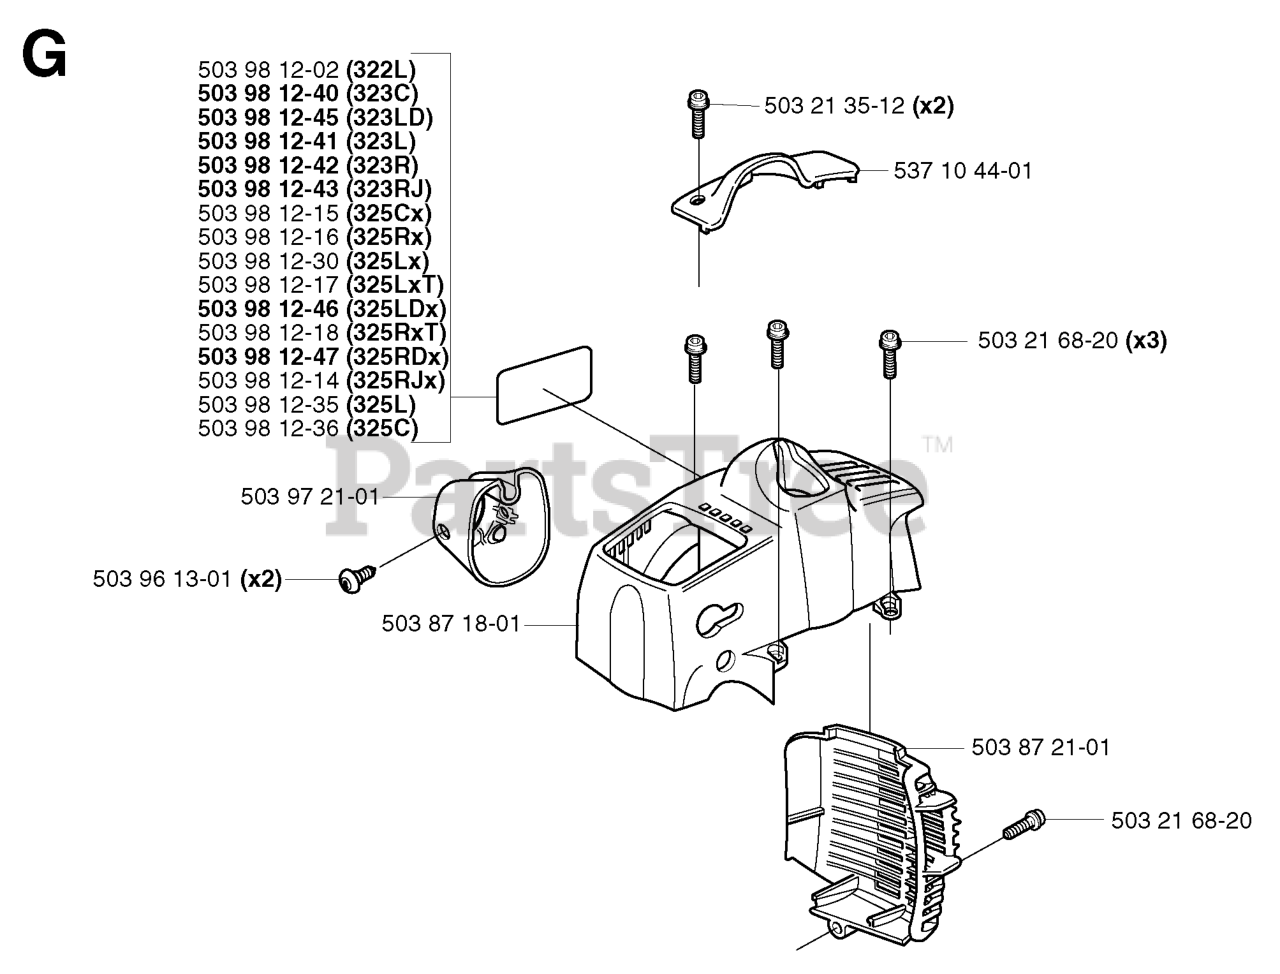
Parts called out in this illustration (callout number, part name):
1	BRACKET.SHIFT.HYDRO
2	SCREW #10-24 X 5/8
3	SCREW 5/16-18 X 3.25
4	WASHER, NYLON FRICTION
5	THRUST WASHER
6	WASHER.20X8.5
7	SRPING.FRICTION.HYDRO
8	NUT.71038.31-18.HEX.NYLOCK
9	BRACKET.HYD.CLUTCH.
10	ARM.CONTRL.PIN.TRACK
11	CONTROL.SHAFT.ASM
12	WASHER.FLAT.1/2
13	CLEVIS PIN
14	PLATE.REAR.HYDRO.TRACK.ORANGE
15	TRANSMISSION 321-0410
16	ROD, BYPASS VALVE
17	BRACKET.HYD.CLUTCH.REAR
18	ARM.CONTROL.HYDRO.SNOW
19	SHAFT.HYD.CLUTCH
20	BOLT.HEX.HD.WASHER.5/16-18X.75
21	BOLT.CARRIAGE.5/16-18X
22	SPRING, BRAKE
23	LOCKNUT.NYLOC.1/4-20
24	RIVET.POP.1/4X.475
25	ARM.HYD.CLUTCH
26	SPRING, TRACTION IDLER
27	RETAINER CLIP
28	BRACKET, ANTI-ROTATE
29	STRAP.TORQUE.HYDRO
30	COVER.TRANSMISSION.TRACK.BLACK
31	SCREW1032X.500
32	RP ROD.HYD.CLUTCH
33	E-RING.RETAINER.REINFORCED.375
34	SCREW 5/16-18X1
35	TANK.EXPANSION.350ML 71328
36	HOSE.EXPANSION.TANK.TRACK
37	CLAMP.SPRING.HOSE.795
38	SCREW, HEX HEAD, TAPPING
39	WASHER
